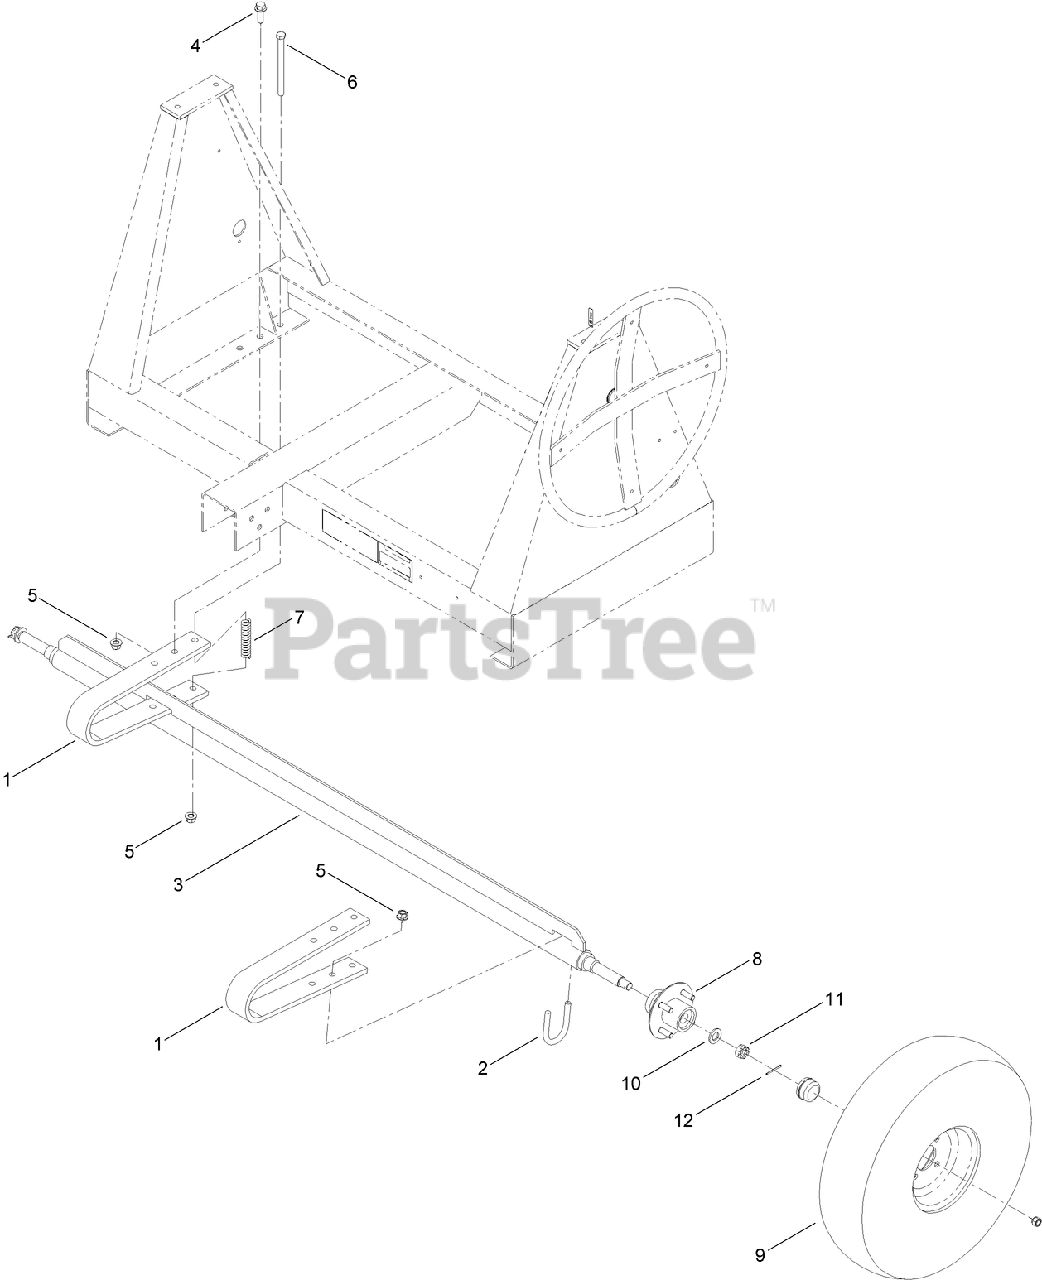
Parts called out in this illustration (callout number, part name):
1	SPRING-LEAF
2	BOLT-U
3	AXLE-SPRING
4	SCREW-HHF
5	NUT-LOCK
6	SCREW-HH
7	SPRING-COIL
8	HUB ASM
9	TIRE AND RIM ASM
10	WASHER-FLAT
12	PIN-COTTER
